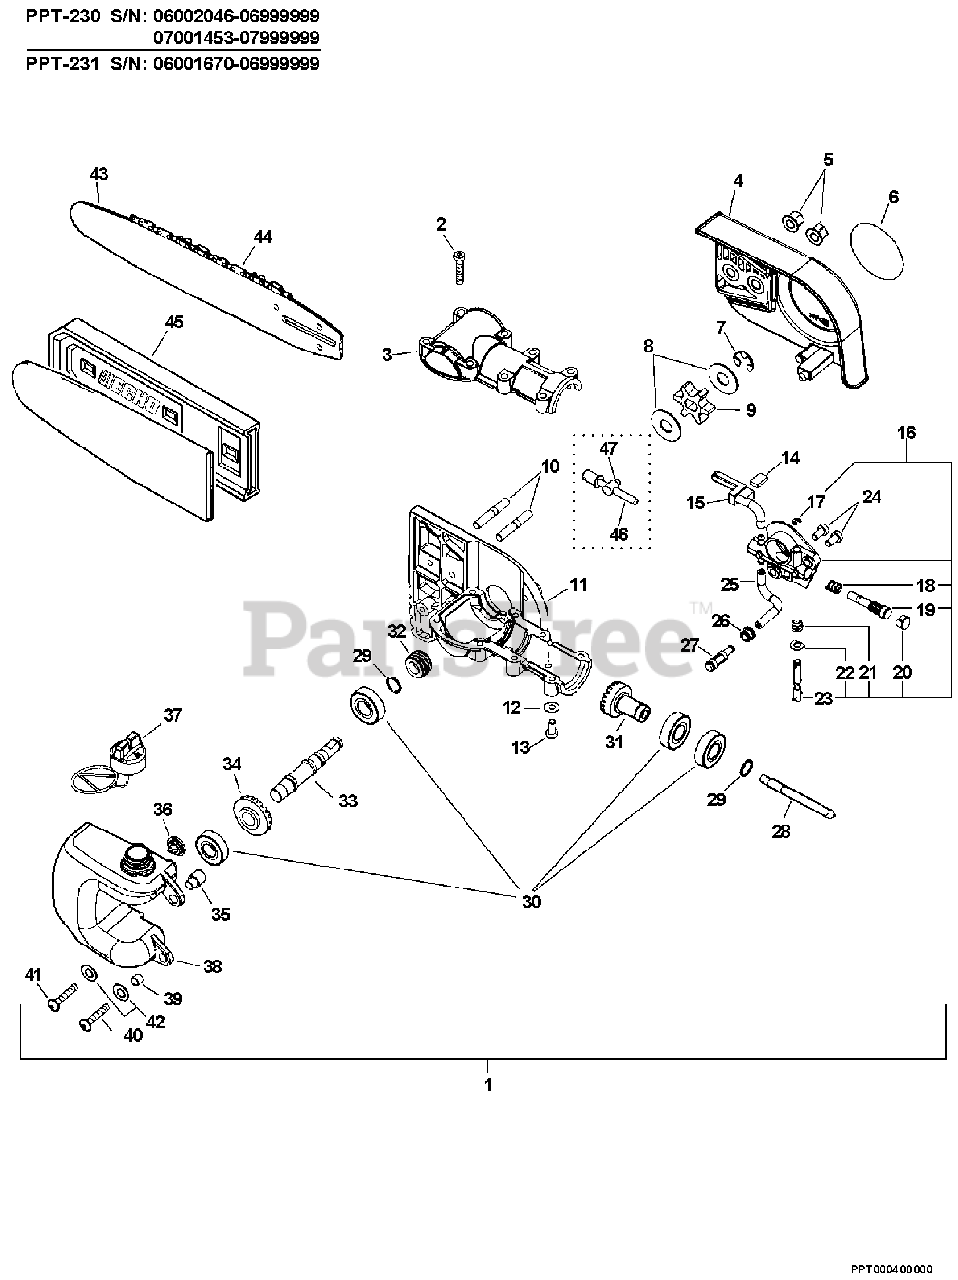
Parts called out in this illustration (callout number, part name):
1	OILER/GEAR CASE ASSY
2	SCREW - 5X25
3	CASE, GEAR - UPPER
4	GUARD, SPROCKET
5	NUT - 6 -- FLANGE
6	LABEL - ECHO
7	RING, RETAINING
9	SPROCKET, DRIVE
10	STUD - 6
11	GEAR CASE ASSY - LOWER
12	WASHER - 5
13	SCREW - 5X10
14	PAD, FOAM
15	PIPE, OIL OUTLET
16	AUTO-OILER ASSY
17	RING, RETAINING
18	SPRING, PLUNGER
19	PLUNGER ASSY
20	CAP, OIL PUMP
23	NEEDLE, ADJUST
24	SCREW - 5X10
25	PIPE - 3X6X75 -- BLACK
26	GROMMET
27	FILTER, OIL
28	CONNECTOR, SHAFT
29	RING, RETAINING - 12
30	BEARING, BALL - 6001
31	GEAR - BEVEL
32	GEAR - WORM
33	GEAR - SHAFT
34	GEAR - BEVEL
37	CAP ASSY
38	TANK, OIL
40	SCREW - 5X16
41	SCREW - 5X25
42	WASHER - 5
43	GUIDE BAR - 10" (25cm) Intenz
44	SAW CHAIN - 10" (25cm)
45	COVER, GUIDE BAR - 10" (25cm)
46	SCREW, TENSIONER
47	TENSIONER, CHAIN
